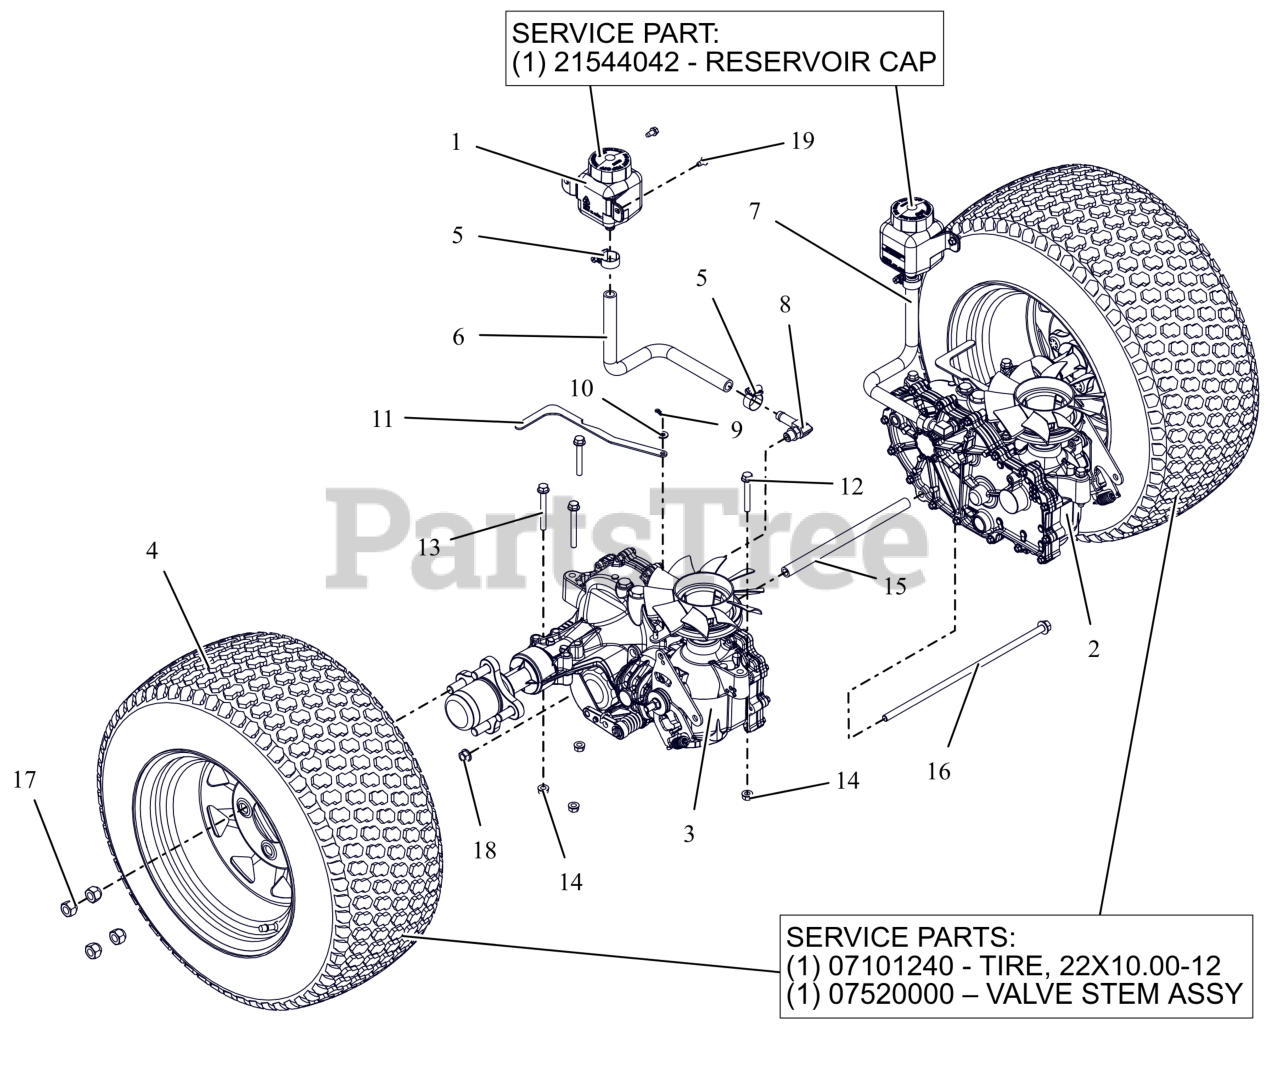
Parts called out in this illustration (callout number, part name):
1	TANK, EXPANSION
1	CAP, HYDRO RESERVOIR REPLAC.
2	TRANSAXLE, ZT3200 - LH
3	TRANSAXLE, ZT3200 - RH
4	ASM, WHL/TIRE 22X10-12 LG BLK
4	TIRE, 22X10.00-12
4	VALVE STEM ASS'Y
4	TUBE 22,23&24X8.50/9.50/10.00/10.50/12.00-12
5	CLAMP,.88 DIA. HOSE
6	HOSE, FORMED EXPANSION -HD RH
7	HOSE, FORMED EXPANSION -HD LH
8	FITTING, HYD (90 DEG)
9	PIN, HAIR #225 .072X1.09
10	WSHR,FLT .281X.625X.065 ZCC
11	BRKT, VALVE DUM
12	BLT,HEX-FLG .31-18X2.25 G5 ZCC
13	BLT,HEX-FLG .31-18X2.75 G5 ZCC
14	NUT,LK-CTR-FLG .31-18 GF ZCC
15	SPCR, TRANSAXLE .406 ID X .630 OD X 9.95LG (BLACK)
16	BLT, HEX-FLG 0.375-16X13 GR5 ZC120
17	NUT, WHEEL .50-20 ZCC
18	NUT-LK-TOP-FLG .38-16 ZC120
19	SCR-TAP .25-20X.50 HWH ZCC
